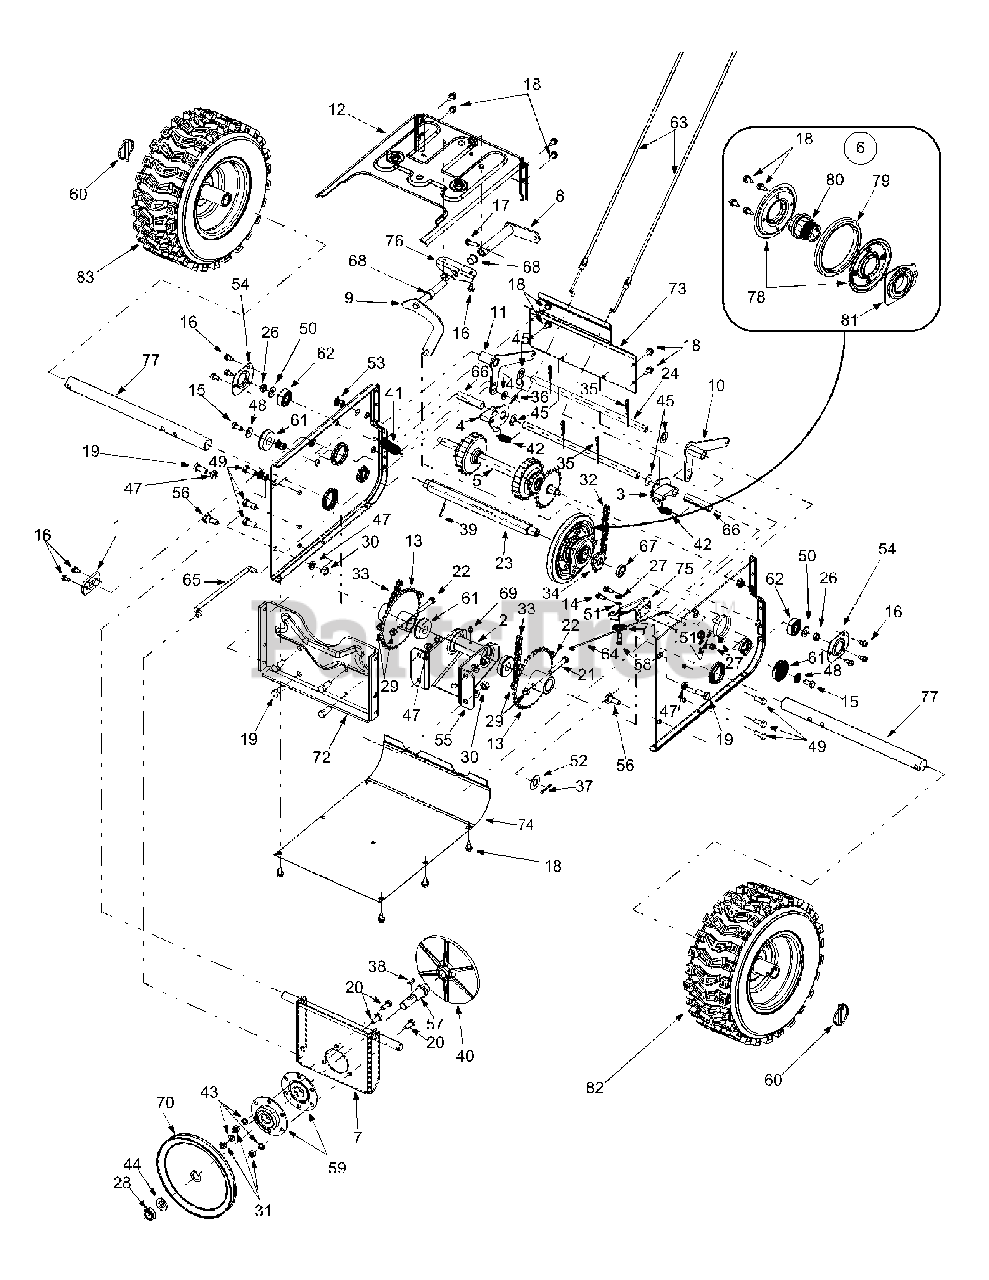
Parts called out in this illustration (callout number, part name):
1	Pivot Support Bracket
2	Spacer, .6725 x 1.125 x 2.485
3	Dogg Assembly LH
4	Dogg Assembly RH
5	Shaft Assembly
6	Friction Wheel Assembly
7	Support Bracket Assembly
8	Shift Arm Assembly
9	Shift Rod Assembly
10	Auger Actuator Bracket Assy.
11	Drive Actuator Bracket Assy.
14	Hex Screw, 1/4-28 x .625"
15	Hex Screw, 5/16-18 x .625"
16	Self-tapping Screw, 1/4-20 x .5
17	Self-tapping Screw, 1/4-20 x 1"
18	Self-tapping Screw, 1/4-14 x .625"
19	Hex Screw 3/8-16 x .880"
20	Hex Screw 5/16-18 x .75"
21	Hex Screw 5/16-18 x 2"
22	Hex Screw 5/16-18 x 1.75"
23	Hex Shaft: Drive
24	Actuator Shaft
25	Actuator Drive Shaft
26	Lock Nut
27	Hex Nut 1/4-28
28	Jam Lock Nut
29	Hex Lock Nut
30	Hex Nut 3/8-16
31	Hex Nut 5/16-18
35	Hairpin Clip
36	Hairpin Clip
37	Cotter Pin
40	Drive Plate
41	Extension Spring
42	Extension Spring
43	Lock Washer 5/16
44	Lock Washer 5/8
45	Flat Washer
46	Flat Washer
47	Lock Washer
48	Bell Washer
49	Self-tapping Screw, 5/16-12 x .75
50	Flat Washer
51	Lock Washer
52	Flat Washer
53	Nut Insert, 3/8-16
54	Bearing Retainer Bracket
55	Axle Bearing Support Bracket
56	Shoulder Screw
57	Spindle: Drive Plate
58	Shoulder Screw 1/4-28 x .375"
59	Bearing Housing Assembly
61	Ball Bearing
62	Ball Bearing
63	Steer Cable
64	Auger Idler Cable
65	Drive Clutch Rod
66	Split Spacer
68	Flange Bearing
69	Lube Fitting, 3/16
70	Drive Pulley
71	Roller Cable
72	Frame Support Bracket
76	Shift Bracket
77	Axle: Wheel
78	Friction Plate
79	Friction Wheel Rubber
80	Friction Wheel Hub
81	Friction Wheel Bearing
82	X-Trac Tire Only
